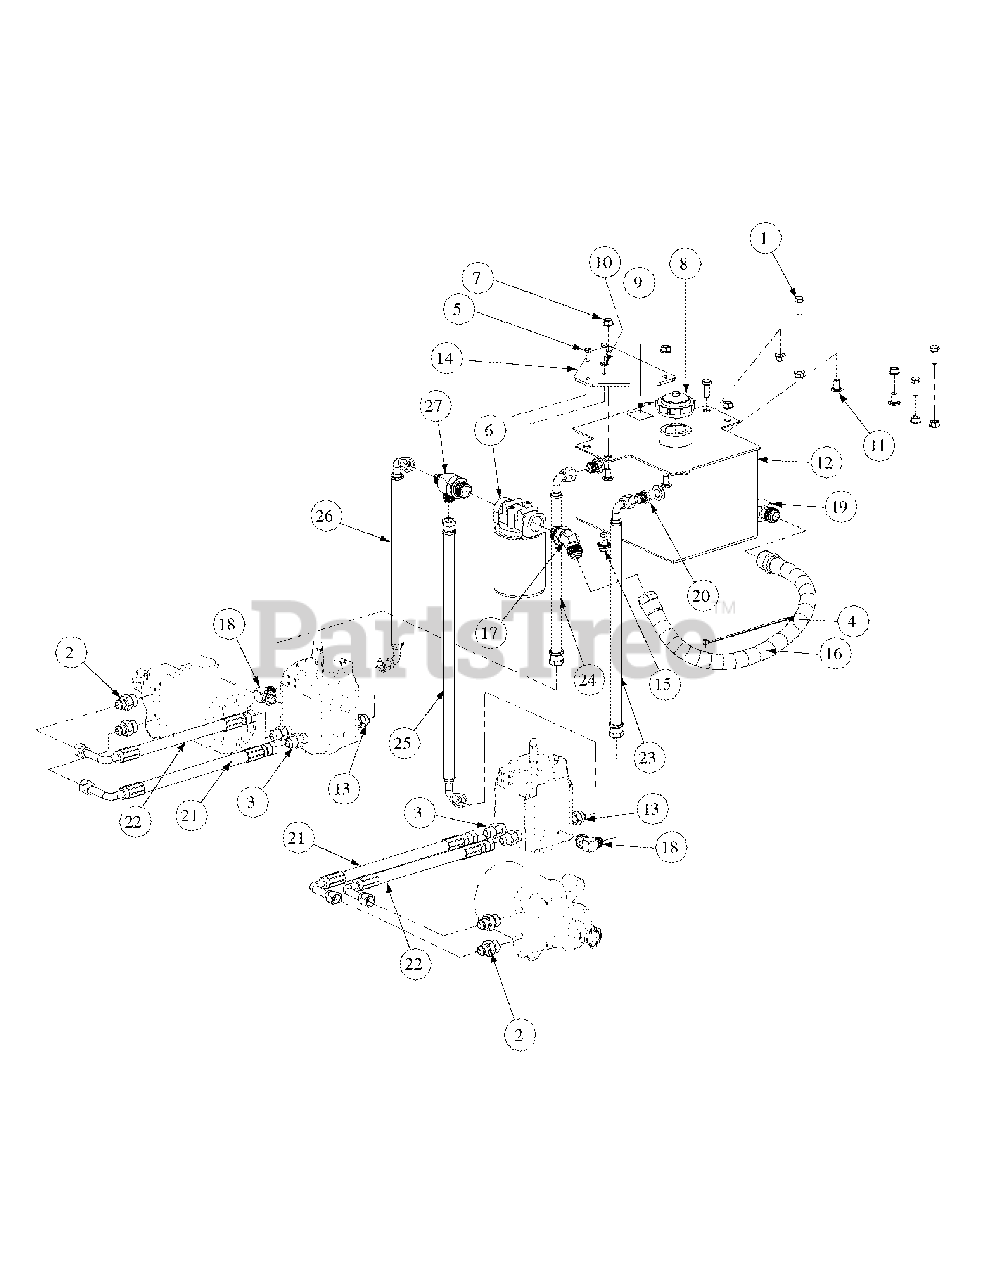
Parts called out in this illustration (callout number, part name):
1	Hex Cap Screw, 3/8-16, 1
2	Fitting 1/2 x 3/4 - O Ring
3	Fitting 1/2 x 3/4 - O Ring to Flare
4	Cable Tie, 3/16 x .05 x 7.4
5	Hex Cap Screw, 1/4-20, .75
6	Filter Head 3/4
7	Hex Nut Flange Lock, 3/8-16
8	Cap, Hydro Oil Tank
9	Decal Oil Only 20W50
10	Lock Washer, 1/4
11	Carriage Bolt, 3/8-16 x .75 LG.
12	Hydraulic Tank Assembly
13	Fitting Connector, 1/2 x 3/8
14	Oil Filter Mounting Plate
15	Oil Pan Drain w/ Seal and Plug
16	Tank to Filter Hose Assembly
17	Connector, 3/4 x3/4
18	Elbow Fitting, 3/8 O-ring, 1/2 Flare
19	Fitting Elbow, 1/2 x 1/2
20	Fitting, 3/8 NPT, 1/2 Flare
21	Long Pressure Hose Assembly
22	Short Pressure Hose Assembly
23	17.75" Return Hose Assembly, RH
24	14" Return Hose Assembly, LH
25	21.25" Supply Hose Assembly, RH
26	15.50" Supply Hose Assembly, LH
27	Tee Fitting, 3/4 x 1/2 x 1/2
